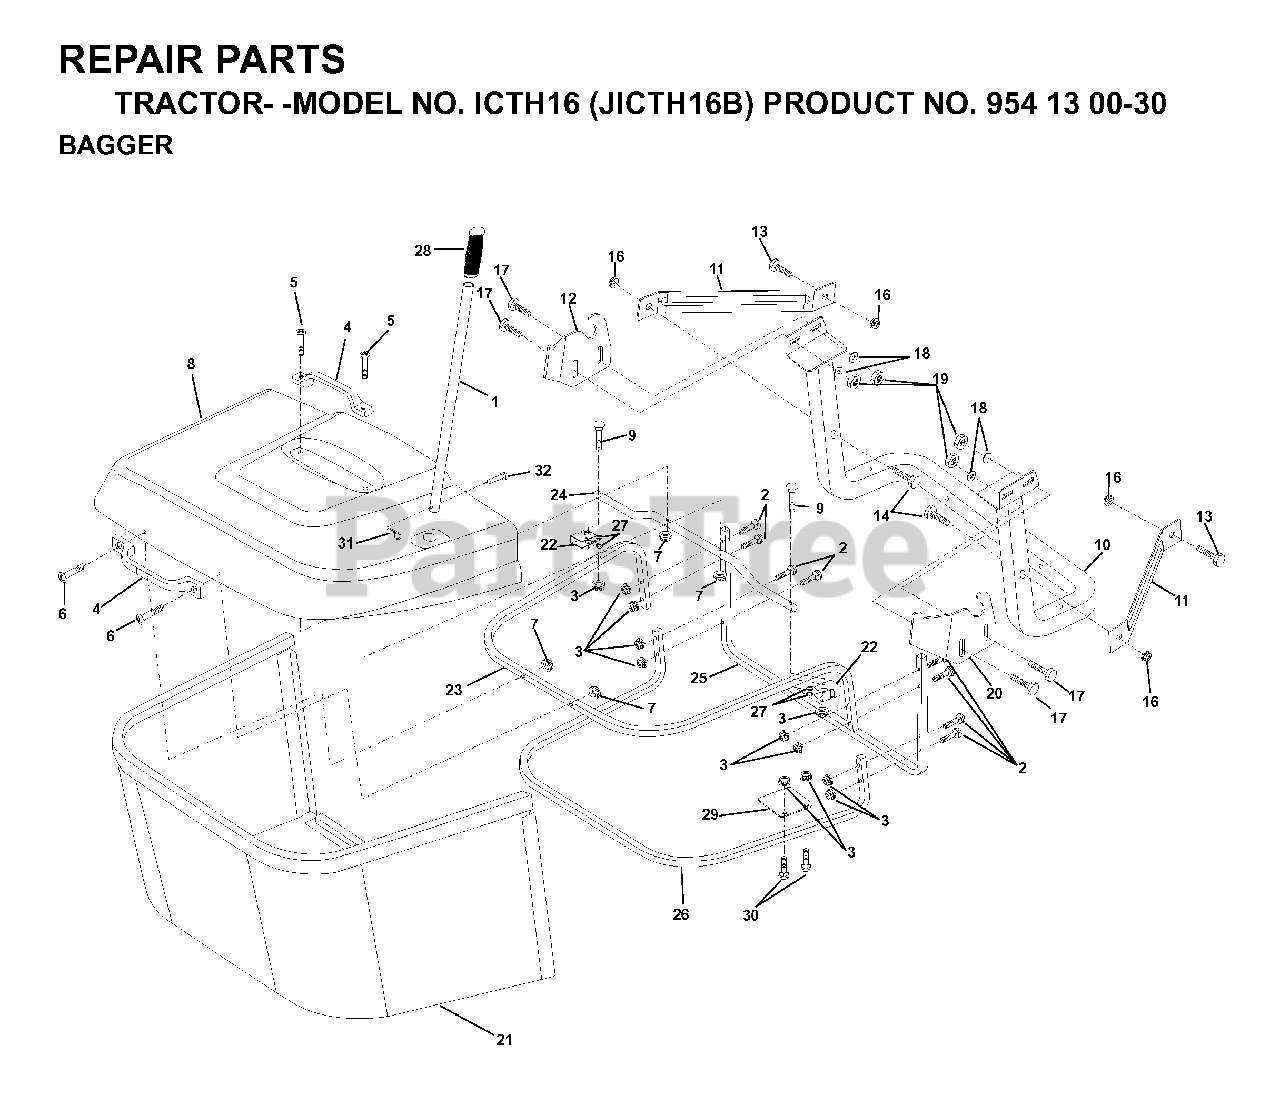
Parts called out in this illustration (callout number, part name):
1	TUBE HANDLE
3	NUT T
5	SCREW.PAN.HEAD
11	BRACKET
16	NUT LOCK FLG 3/8-16 UNC
17	BOLT
19	NUT.71038.31-18.HEX.NYLOCK
21	BAG
22	BRACKET
23	TUBE
24	TUBE
26	TUBE
28	GRIP.HANDLE.BLACK
31	RETAINER M
32	RIVET,DRILLED
